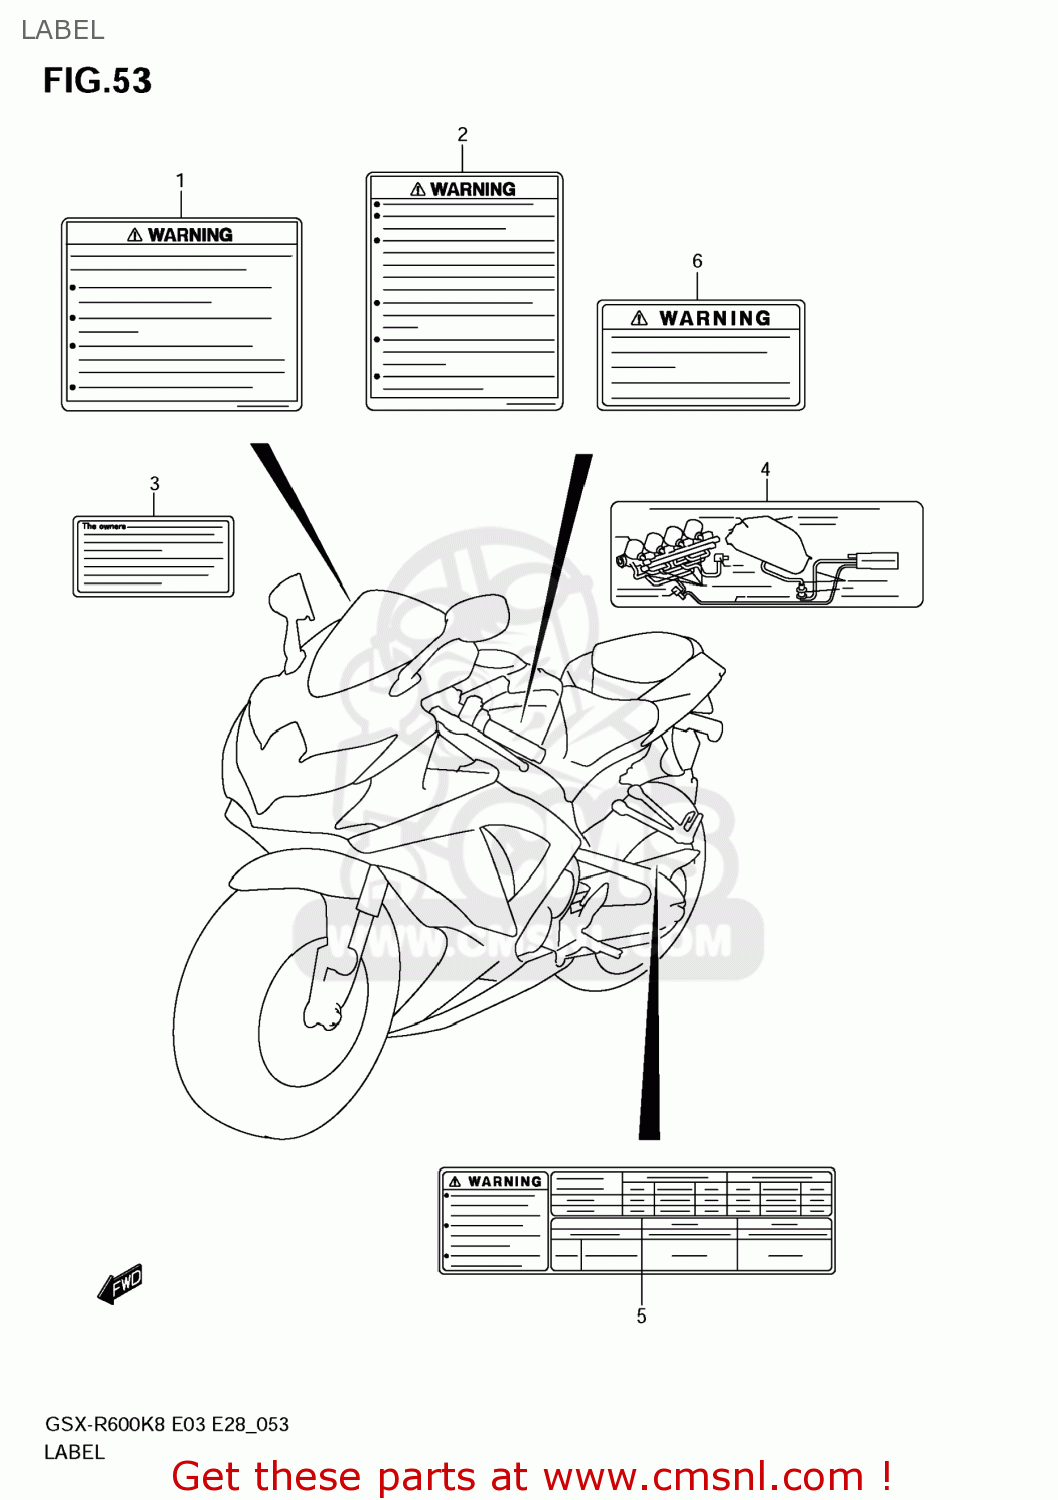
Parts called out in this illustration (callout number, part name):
1	LABEL,GENERAL WARNING
2	LABEL,SCREEN
3	LABEL,MANUAL NOTICE
4	LABEL,VACUUM HOSE ROUTING
5	LABEL,TIRE INFORMATION
6	LABEL,WARNING STEERING
7	MANUAL,OWNER'S
